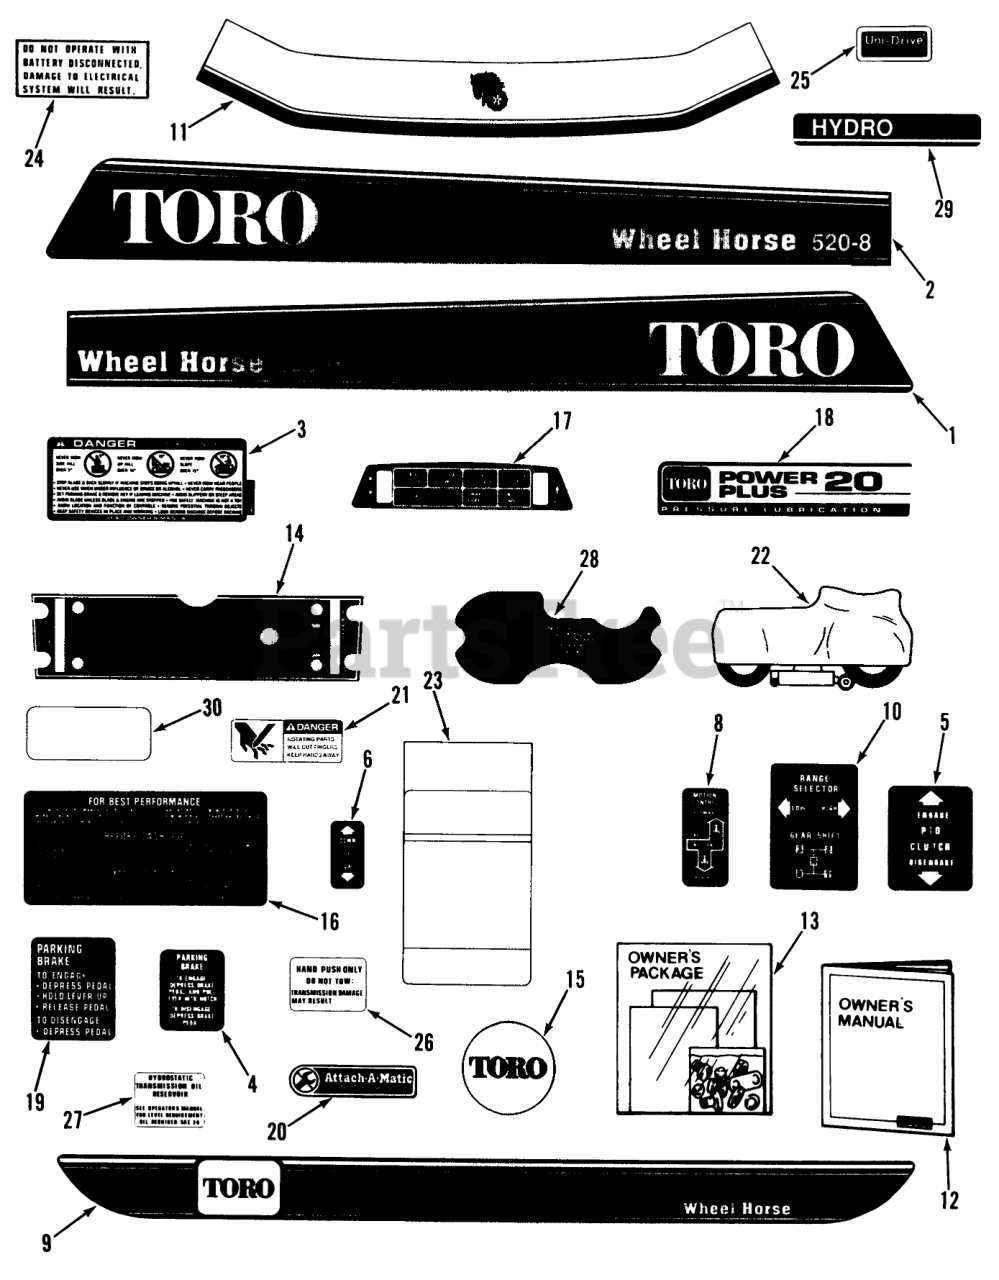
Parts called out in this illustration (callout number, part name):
1	DECAL-HOOD 520-8 R H
2	DECAL-HOOD 520-8 L H
3	DECAL-DANGER
4	DECAL-PARKING, BRAKE
5	DECAL PTO CLUTCH
6	DECAL-LIFT
8	DECAL-MOTION CONTROL
9	DECAL-FENDER
10	DECAL-SHIFT PATTERN
11	DECAL-FRONT HOOD
12	Operator-s Manual-Tractor 520-H
13	Loose Parts Package
14	DECAL-FRONT PANEL
15	NAME-PLATE TORO LOGO
16	Decal-Rear Hood
17	DECAL-INDICATOR LITE
18	DECAL-PWR PLUS 20 PL
19	DECAL-PARKING BRAKE
20	Decal-Attac-O-Matic
21	DECAL-DANGER
22	Plastic Cover
23	MAINTENANCE-DECAL
24	DECAL ELECT SYSTEM
25	Decal-Unidrive
26	DECAL-DO NOT TOW
27	Decal-Danger
28	DECAL-SEAT LIFTER
29	DECAL-MODEL HYDRO
30	DECAL-OVERLAY
